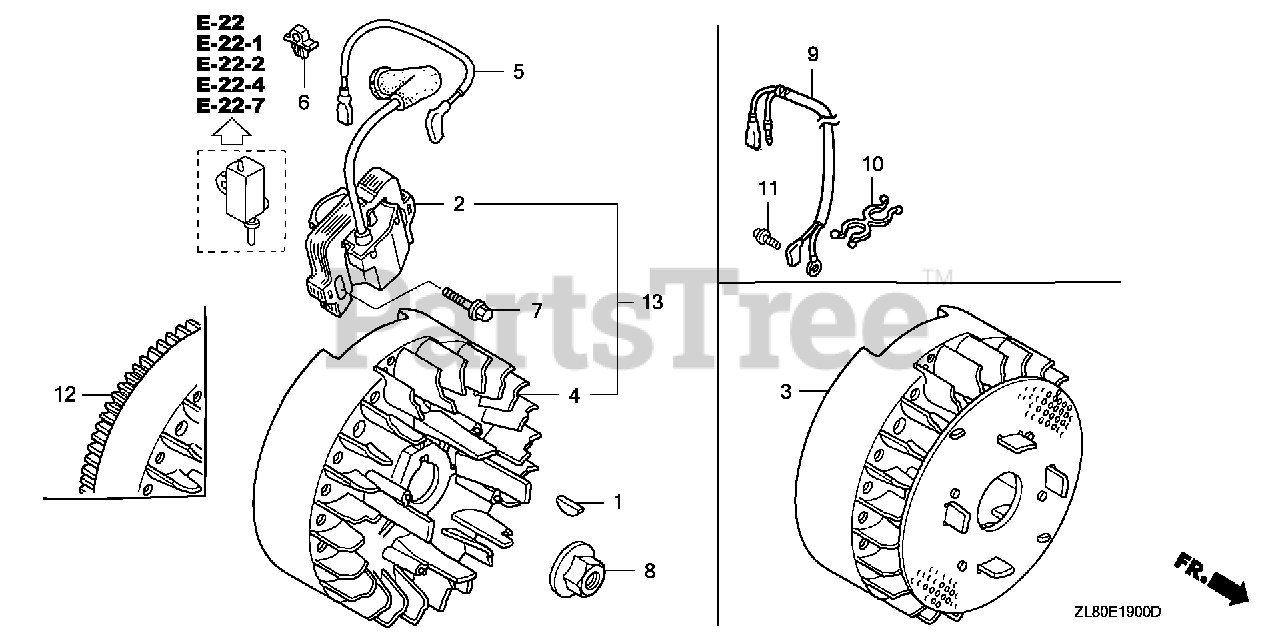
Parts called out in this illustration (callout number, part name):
1	KEY, SPECIAL WOODRUFF (25X18)
2	COIL ASSY., IGNITION (PHELON) (USE FOR F/W OF PHELON)
2	COIL ASSY., IGNITION (PHELON)
5	WIRE, STOP SWITCH
6	HOLDER, STOP SWITCH WIRE Use up to Engine SN 2056819.
7	BOLT, FLANGE (6X20) (CT200)
8	NUT, SPECIAL (14MM)
12	FLYWHEEL COMP.(PHELON) (USE FOR IGN. COIL OF PHELON) (USE FOR PHELON IGNITION COIL)
12	FLYWHEEL COMP. (PHELON) (USE FOR IGN. COIL OF PHELON) (NA USE ALT:06311-Z0J-930)
